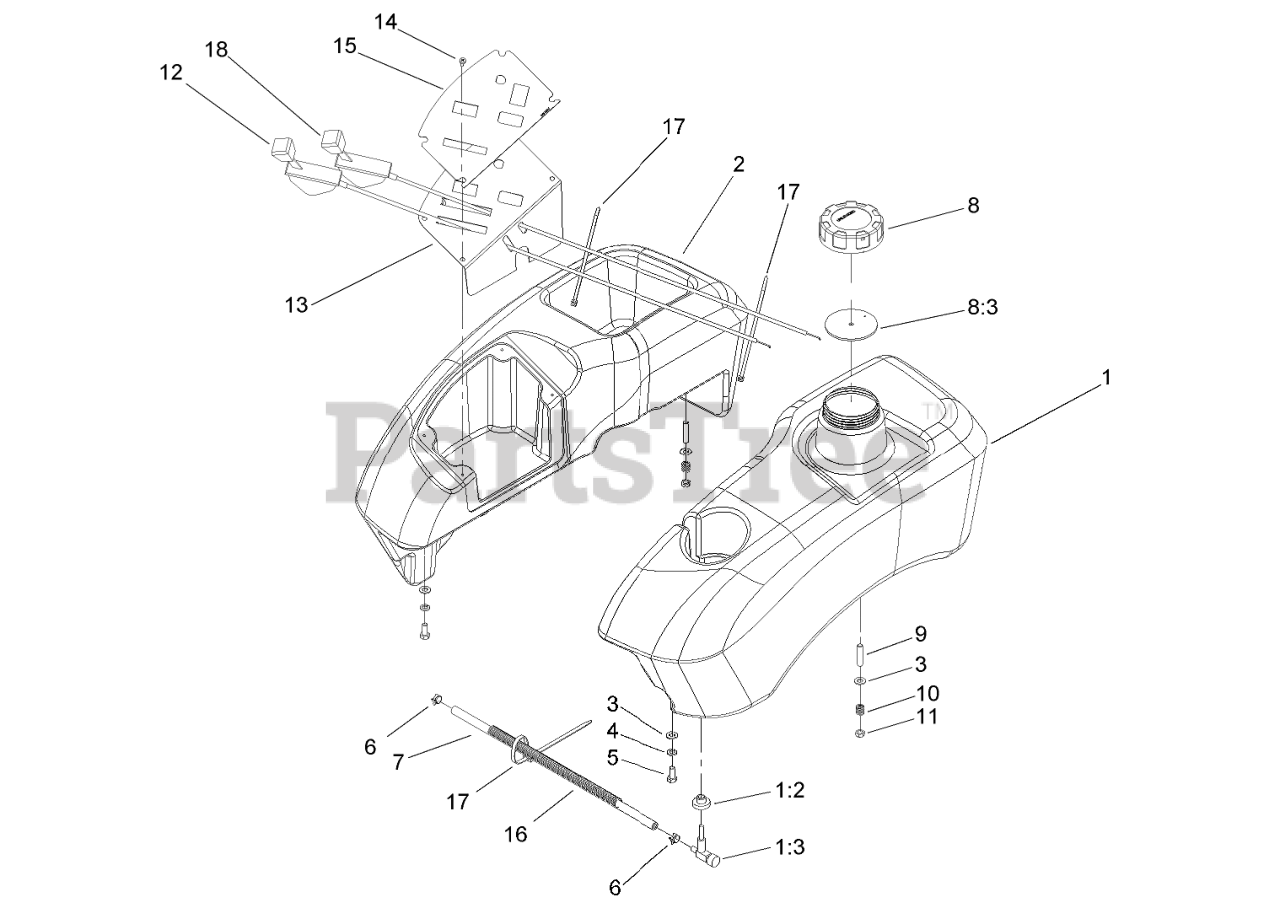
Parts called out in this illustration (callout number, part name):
1	Fuel Tank ASM
1:2	BUSHING
1:3	VALVE-FUEL
2	Tank-Console
3	WASHER-PLAIN
4	WASHER-LOCK
5	SCREW-HH
6	CLAMP-HOSE
7	HOSE-FUEL
8	GAS CAP ASM
8:3	GASKET-CAP, GAS
10	SPRING-TANK, FUEL
11	NUT-LOCK, NI
12	CABLE-THROTTLE
13	PANEL-CONTROL
14	SCREW-PPH
15	DECAL-PANEL, CONTROL
16	COVER-CONDUIT
17	TIE-CABLE
18	CABLE-CHOKE
